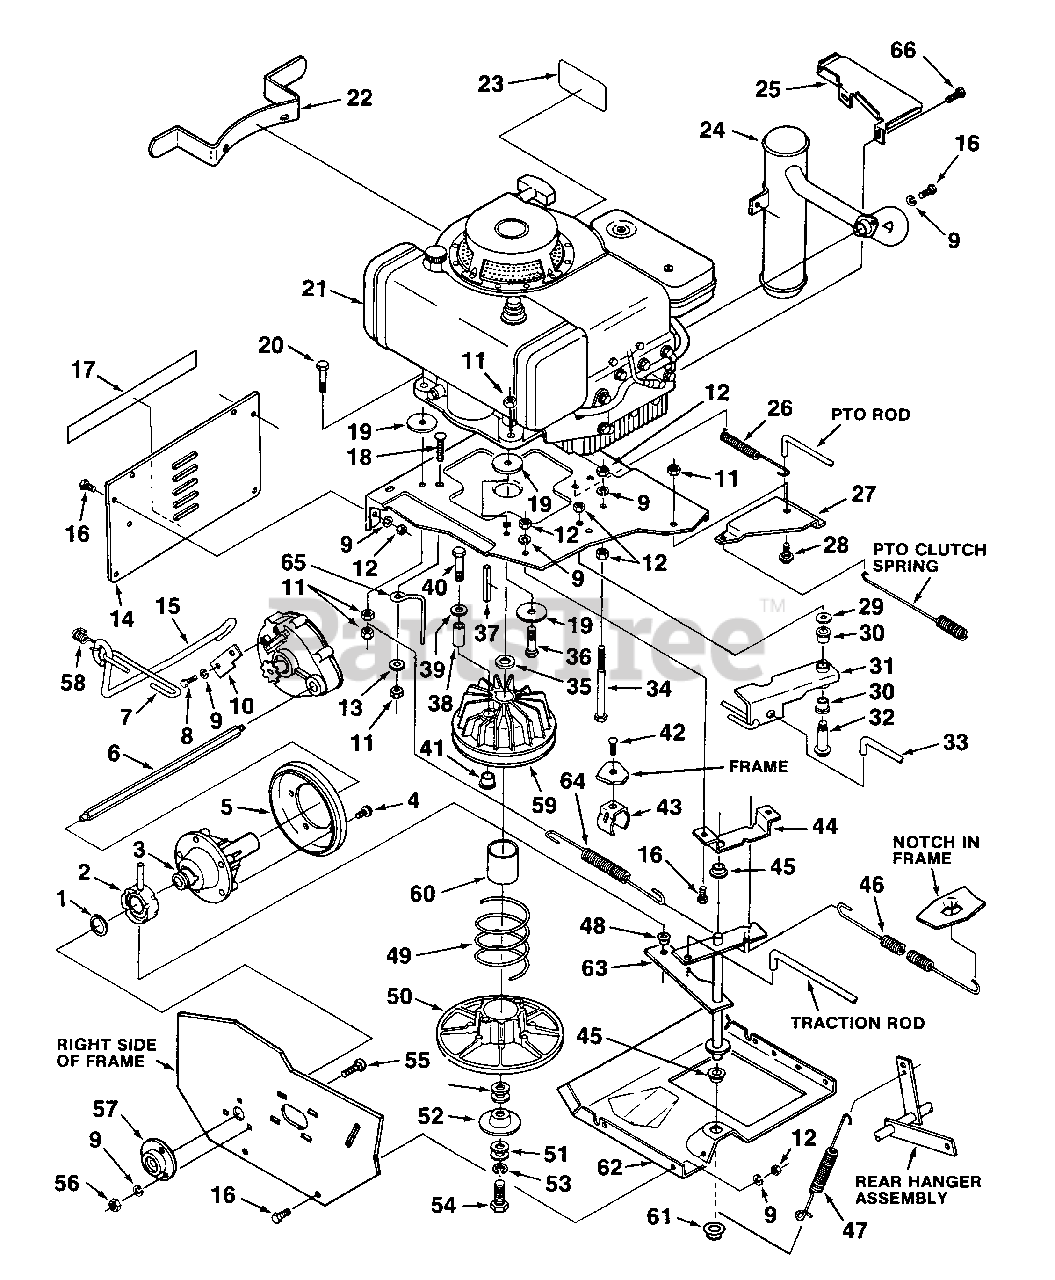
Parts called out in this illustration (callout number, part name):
1	RING- Snap
2	SLEEVE & BEARING ASSY.
3	HUB- Driven
4	SCREW- 1/4-20 x.750
5	WHEEL- Drive
6	SHAFT- Hex
7	LINK- Connecting
9	WASHER-
10	RETAINER- Rod
12	NUT
13	WASHER
15	ROD- Brake
16	SCREW-
17	DECAL- 7"
18	BOLT- Rd sq neck
21	ENGINE- B&S 8HP
24	MUFFLER
25	SHIELD- Muffler
27	CRANK- Bell
31	BRAKE ASSEMBLY
33	ROD- Brake
34	BOLT- Hex
35	WASHER- Flat
38	SPACER- Pulley
39	WASHER
44	BEARING- Support pivot
46	SPRING- Extension
48	BUSHING- Pin
49	SPRING- Compression
50	DISC- Drive (w/bushing)
57	RETAINER & BEARING
59	PULLEY- Engine w/bushing
62	COVER- Bottom
63	PIVOT SHAFT ASSY
64	SPRING- Neutral reverse
65	GUIDE- Belt
66	SCREW
